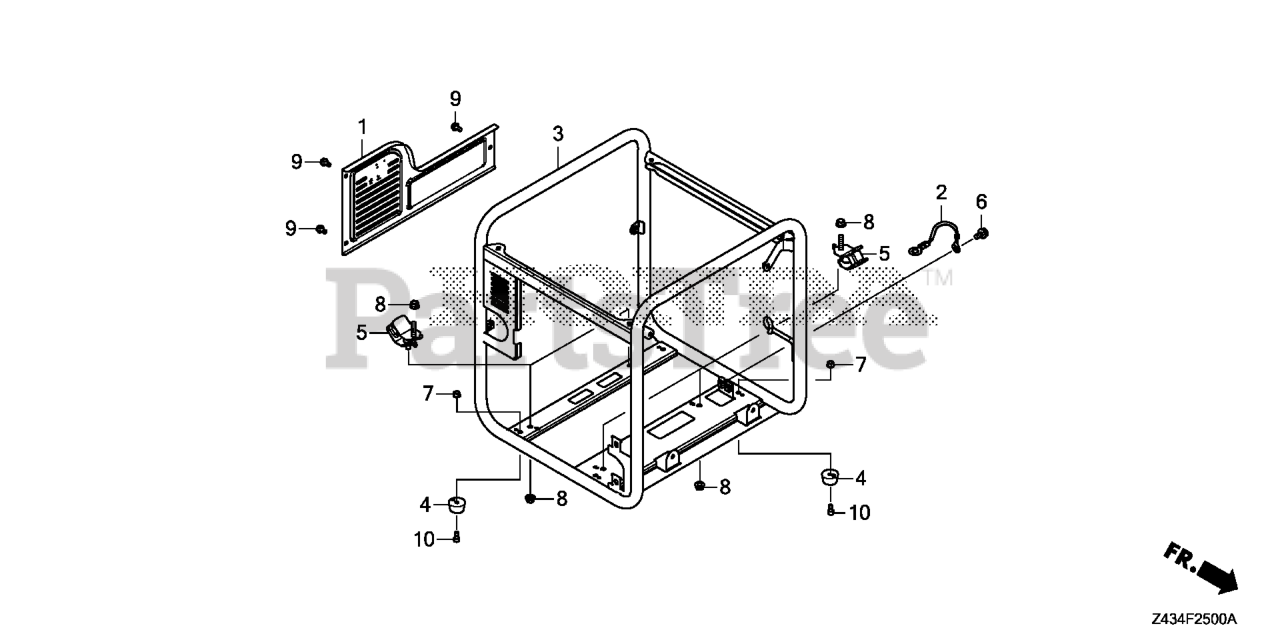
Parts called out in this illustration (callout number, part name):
1	PROTECTOR, MUFFLER *NH105* (MAT BLACK)
2	CABLE, GROUND
3	FRAME *NH105* (MAT BLACK)
4	RUBBER, BASE
5	RUBBER (LOWER)
6	BOLT, GROUND (6X12) (SN)
7	NUT, FLANGE (6MM)
8	NUT, FLANGE (8MM)
9	BOLT, FLANGE (6X12) Use up to Engine SN 1543277.
10	BOLT, SOCKET (6X12)
